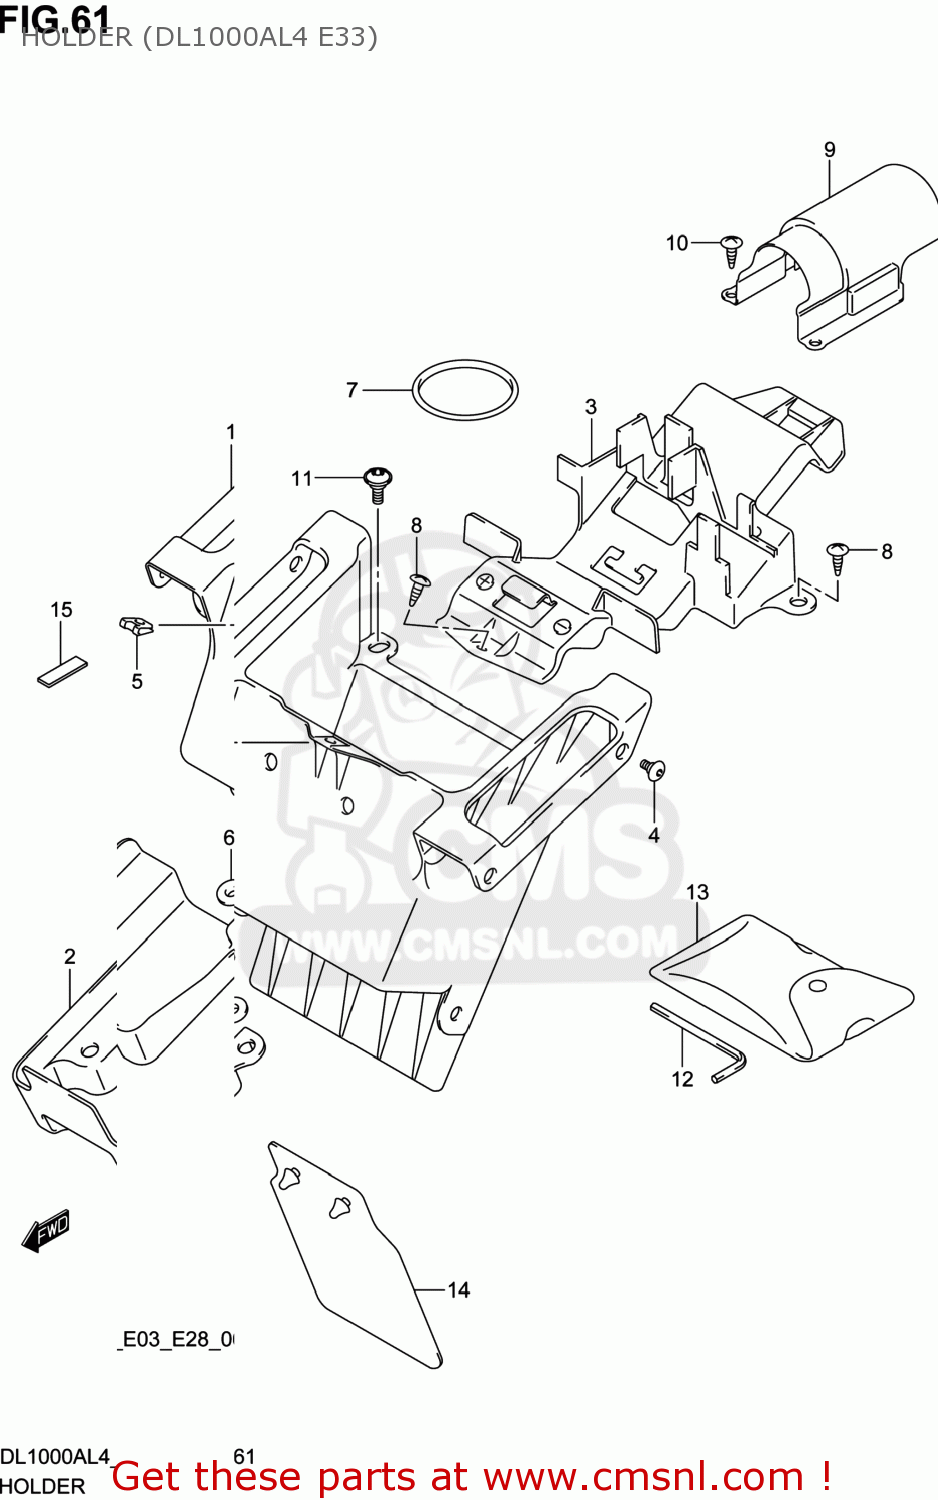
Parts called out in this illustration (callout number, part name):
1	HOLDER,BATTERY
2	COVER,ACTUATOR
3	HOLDER,TOOL
4	SCREW(6X12)
5	NUT
6	WASHER
7	O RING(D:3.5,ID:62.6)
8	SCREW
9	HOLDER,CANISTER
10	SCREW
11	BOLT(5X13)
12	HEXAGON SPANNER,5
13	TOOL ASSY
14	MUDGUARD,RR FENDER
15	CUSHION,PANEL NO.2
